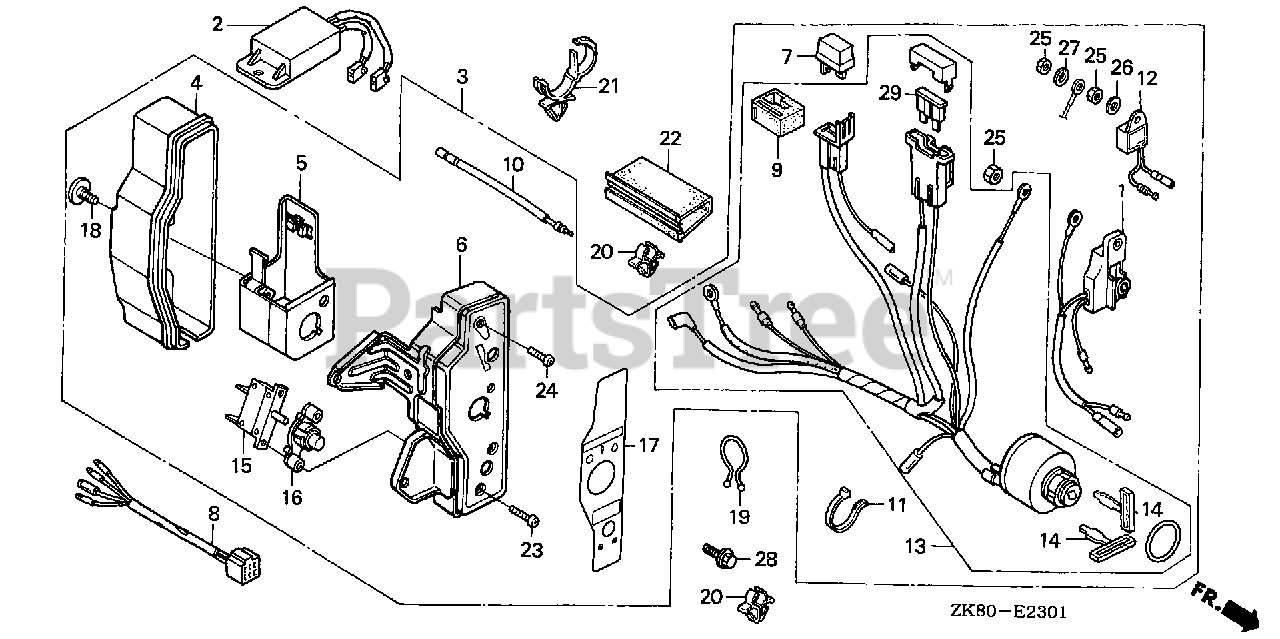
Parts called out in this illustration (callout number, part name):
1	ALERT UNIT, OIL
2	RECTIFIER, REGULATOR
3	BOX ASSY., CONTROL *R280* (INTL-ALERT) (POWER RED)
4	CASE, CONTROL
5	BRACKET, CASE MOUNTING
6	PANEL, CONTROL *R280* (POWER RED)
7	RECTIFIER ASSY., SILICON (SHINDENGEN)
8	SUB-WIRE HARNESS ASSY.
9	SUSPENSION, CONNECTOR
10	SUB-WIRE HARNESS
11	BAND
13	SWITCH ASSY., COMBINATION
14	KEY
15	PROTECTOR, CIRCUIT (1.0A)
16	LENS ASSY., PROTECTOR
17	PANEL, CONTROL BOX (INTERNAL)
17	MARK, CONTROL BOX (EXP)
18	SCREW, SPECIAL (6X12)
19	CLIP, PURSE LOCK
20	CLIP, CORD
21	STRAP, WIRE HARNESS (25MM) (BLACK)
22	TUBE, FASTENER (30MM)
23	SCREW, PAN (3X12)
24	SCREW, PAN (4X12)
25	NUT, HEX. (4MM)
28	BOLT, FLANGE (6X28) (CT200)
28	BOLT, FLANGE (6X10)
29	FUSE, BLADE (5A)
